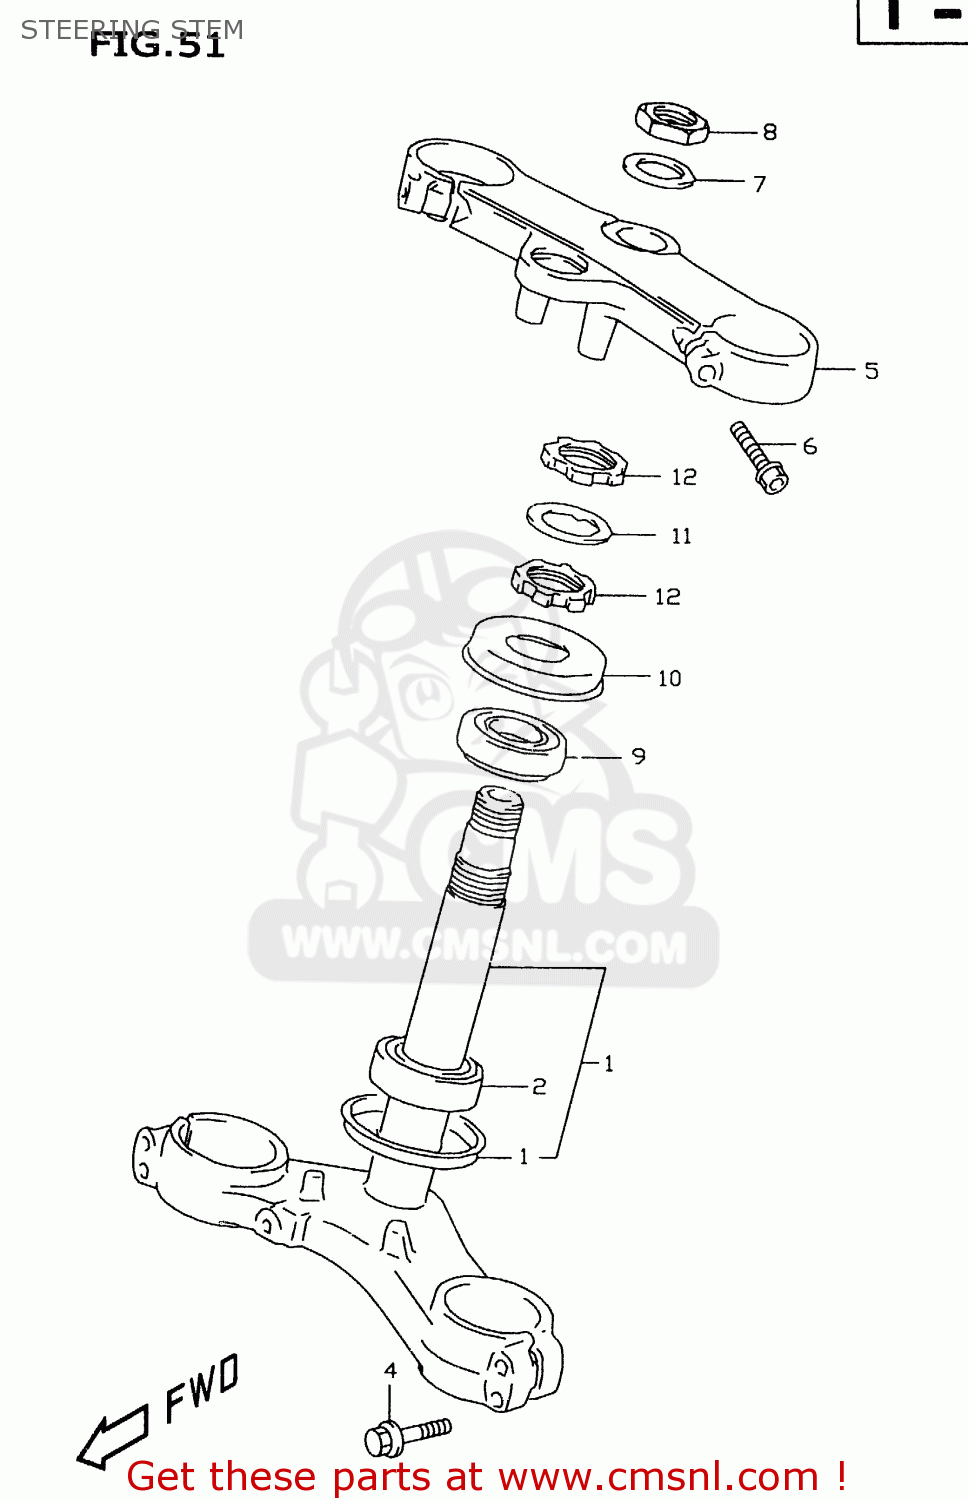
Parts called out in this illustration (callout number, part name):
1	STEM,STEERING
2	BEARING(30X55X17)
3	SEAL,STEERING LWR
4	BOLT
5	HEAD,STEERING STEM
6	BOLT
7	WASHER
8	NUT,STEM HEAD
9	BEARING(30X55X17)
10	SEAL,STEERING UPR DUST
11	WASHER,STEERING STEM
12	NUT,STEERING STEM
